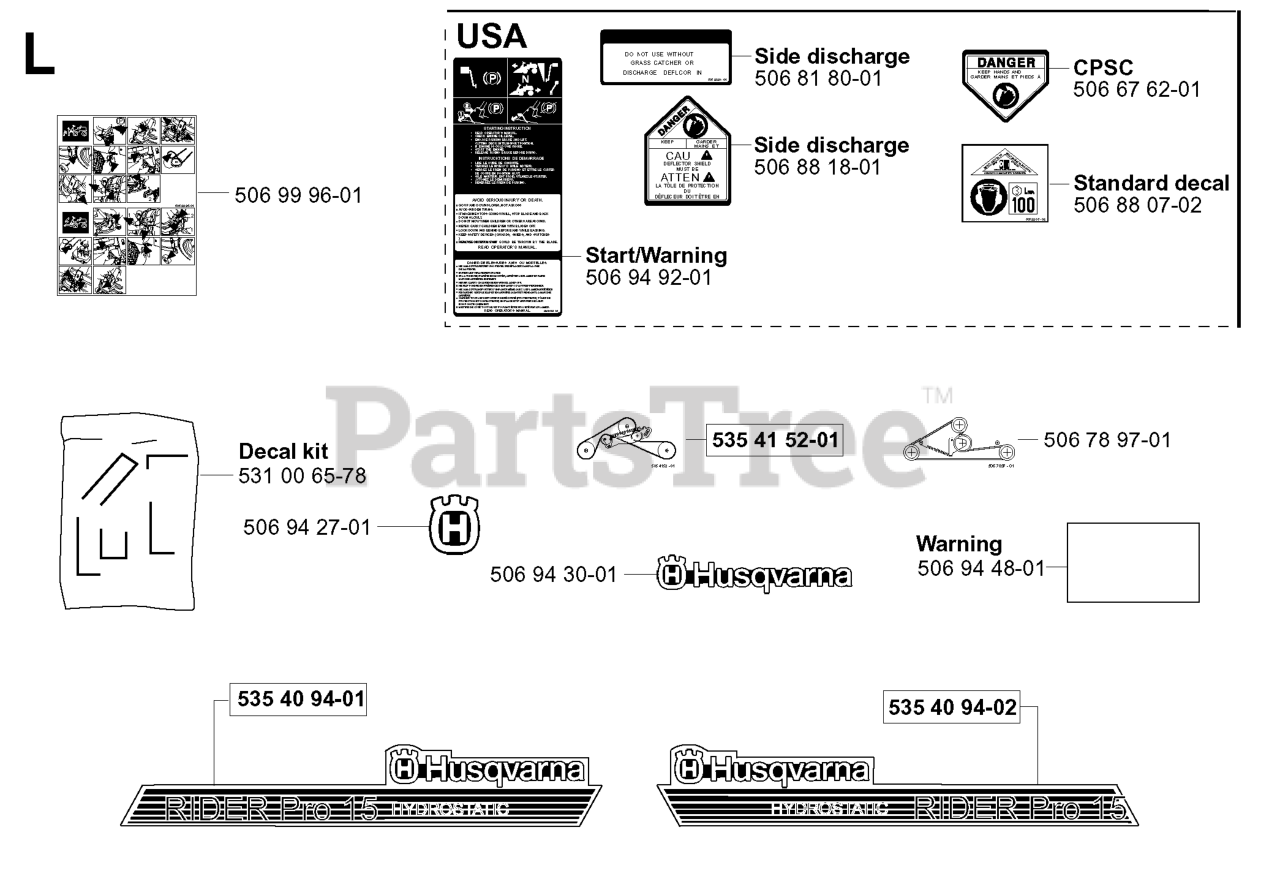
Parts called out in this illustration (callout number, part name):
1	42" DECK KIT
2	RP BOLT 5/16-18 X3/4 ZN/YEL GR
3	BRKT ASM SWAY BAR
4	BRACKET SWAY BAR 42" DECK
5	RETAINER-SPRNG RB
6	BAR SWAY DECK
8	BLADE BOLT
9	LOCKWASHER
10	WASHER.BLADE
11	BLADE.42".MULCH
13	SHAFT ASM VENT
14	HOUSING.MANDREL.VENTED (MACHD)
16	STRIPPER.MANDREL.ROUND.BLACK
18	BOLT
19	BOLT SHD 5/16-18
20	BAFFLE.VORTEX
21	LOCKNUT
23	BRKT, DEFL. MOWER
24	CAP-SLEEVE LT
25	SPRING TORSION
26	NUT PUSH M
27	SHIELD DEFLECTOR
28	Washer 11/32 x 5/8 x 16 Ga SD
29	ROD.HINGE
30	SCREW, WASHER HEAD
31	WASHER
32	PULLEY/MANDREL
33	NUT, FLG TOPLOCK 9/16"
36	FLAT IDLER PULLEY
37	WASHER
44	GUARD MANDREL LH BLACK
45	RETAINER M
46	SCREW.1/4-20X5/8
52	BOLT.SHOULDER.5/16-18
53	ARM BRAKE ASSY
55	ARM IDLER 42" MOWER LT/YT
56	SPACER.RETAINER.MOWER
59	GUARD, BELT
67	KNOB T (3/8 HOLE)
68	BELT V SECONDARY
92	NUT
129	WASHER
131	BOLT D
142	ARM SPRING BRAKE MOWER
143	BRACKET, ARM IDLER
144	DNO KEEPER.BELT.42".CLUTCH.CBL
145	PULLEY
146	BOLT, CARRIAGE IDLER BLACK
147	SPRING EXTENSION
148	IDLER RETURN SPRING
149	SPRING.RETAINER.YELLOW.ZINC
151	BRACKET.CLUTCH.CABLE
152	CLUTCH CABLE 42"
153	WASHER FLAT 3/8"
154	SPRING RETAINER
155	SPRING RETENTION LEVER
156	SPACER.CLUTCH.CABLE
157	ROD CLUTCH CABLE 3/8"
158	SCREW
184	WASHER
